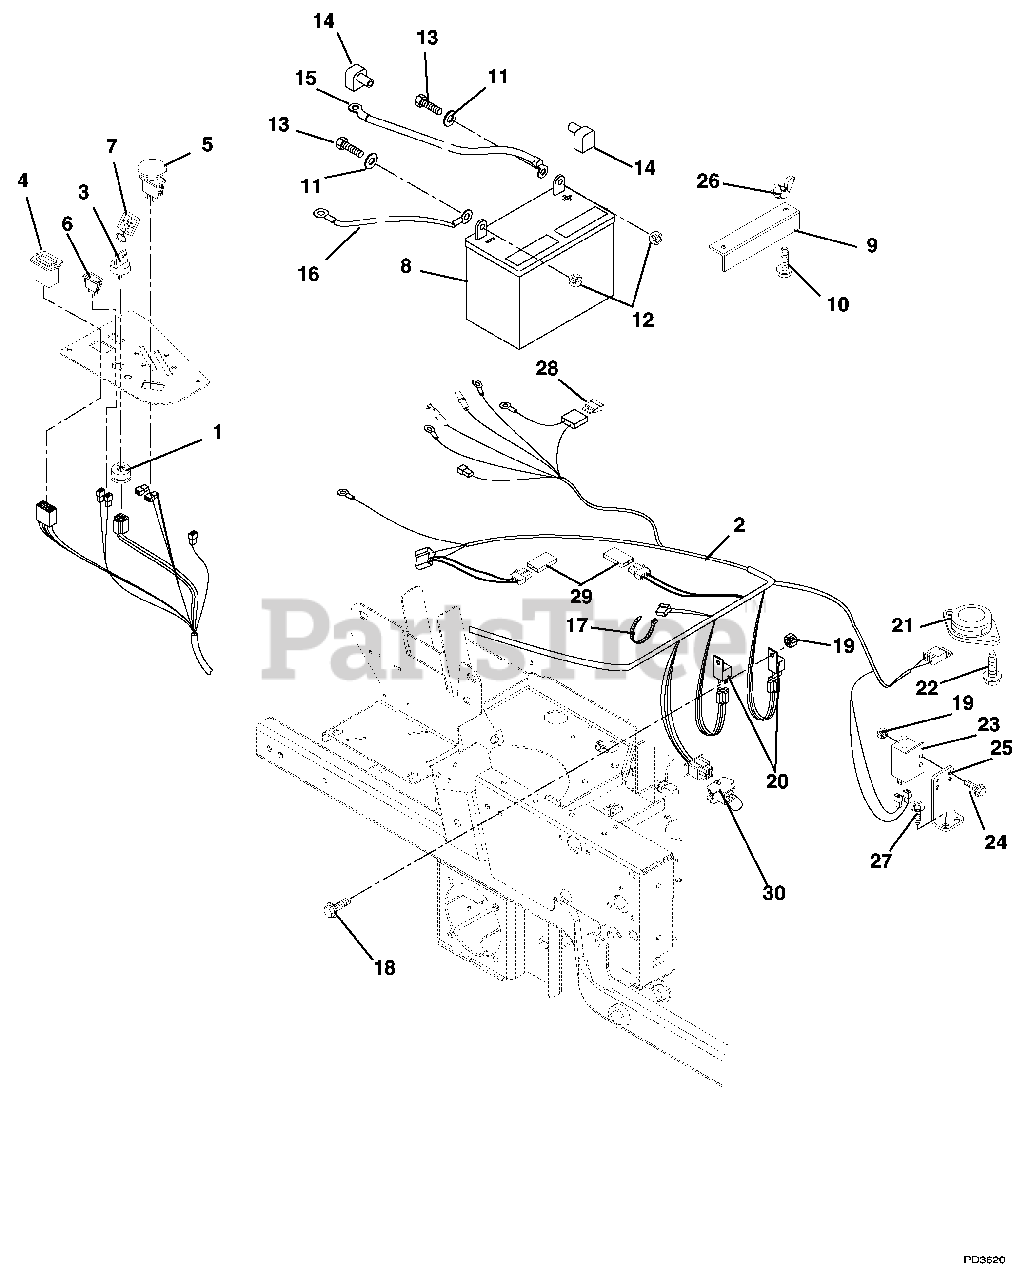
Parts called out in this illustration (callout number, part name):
1	Key Switch
2	Harness, Z-6 Pin (EYE-Q)
3	Key with Shield
4	Hour Meter
5	Switch, Clutch With Retainer Ring
6	Light, Indicator Kit
7	Key Chain
9	Hold Down
10	Bolt, Round Head Square Neck .25-20 x 7.50
11	Washer, Flat Steel .281 x .620 x .065
12	Nut, Locking Top Flange .25-20
13	Bolt, Hex .25-20 x .75 Grade 5
14	Insulator
15	Positive Cable 22"
16	Cable, Negative Battery
17	Cable Tie
18	Screw, Machine 10-24 x .50 Hex Washer Head
19	Nut, Locking Nylon 10-24 With Insert
20	Relay
21	Seat Switch
22	Screw, Tapping 12-24 x .50 Hex Washer Head
23	Switch, Single Pole
24	Screw, Machine 10-24 x .75 Hex Washer Head
25	Mount, Brake Switch
26	Nut, Locking Wing .25-20
27	Screw, Tapping .25-20 x .50 Hex Washer Head
28	Fuse, 30 Amp
29	Diode, Connector Shell
30	Harness, Jumper (EYE-Q)
